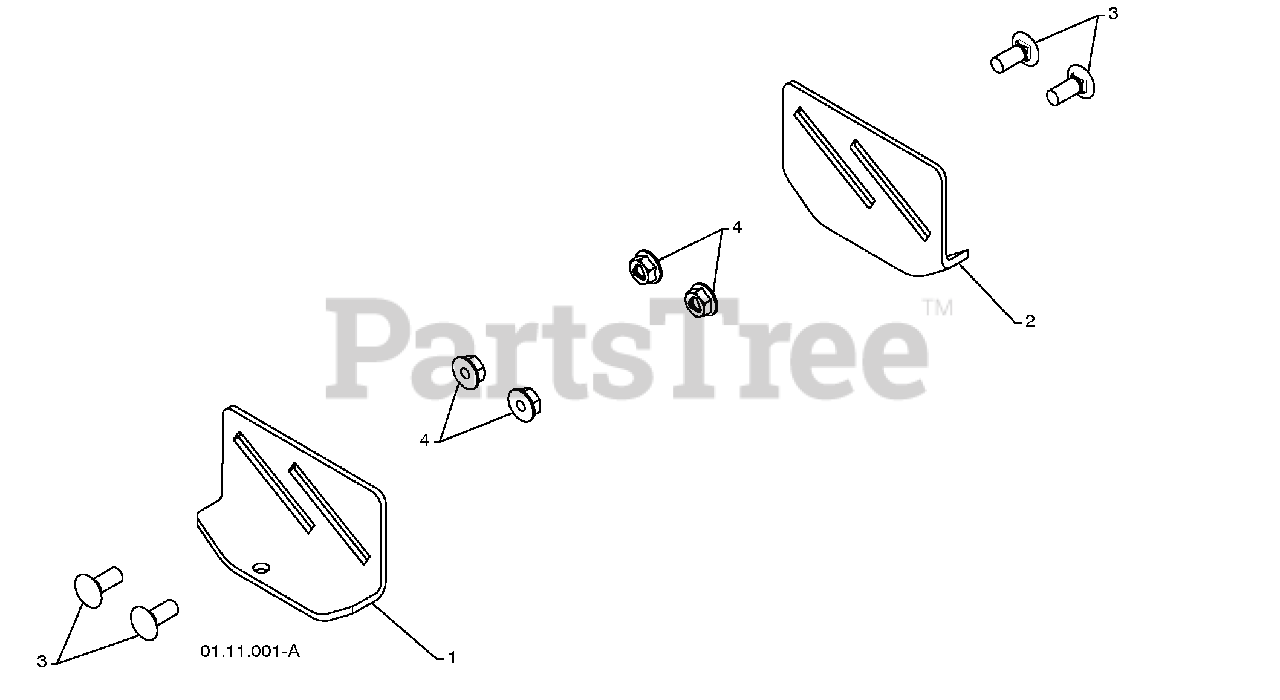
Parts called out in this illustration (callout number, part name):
1	SKID PLATE LH
2	SKID PLATE RH
3	CARRIAGE BOLT 5/16-18 X .75
4	NUT 5/16-18
